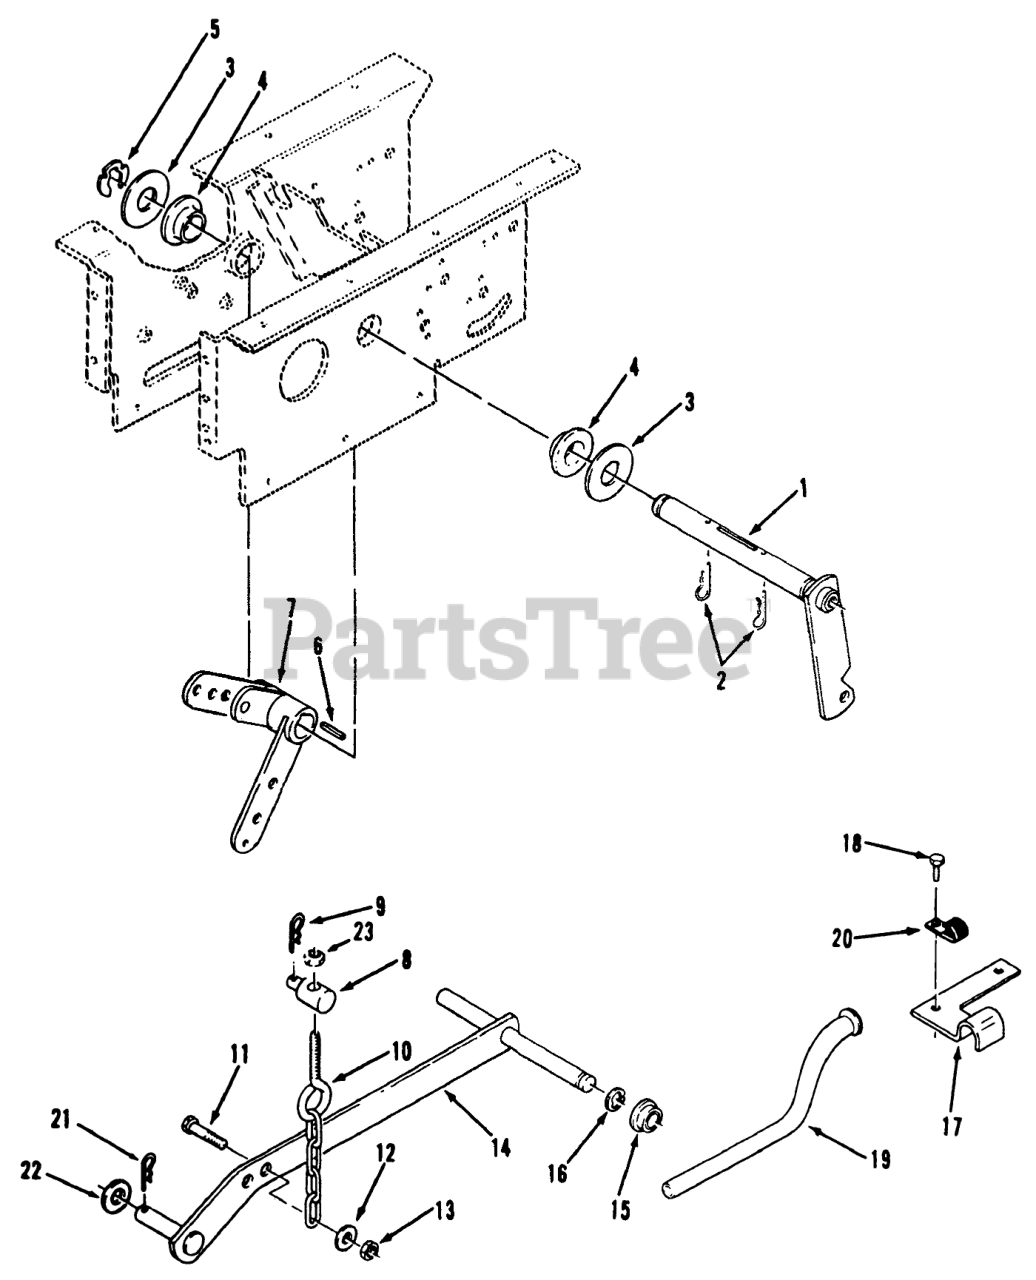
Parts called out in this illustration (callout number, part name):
1	WLDMT-LIFT ARM
2	Pin-Cotter
3	WASHER-FLAT
4	BEARING-FLANGE
5	Retainer
6	KEY-SQUARE
7	LIFT LEVER ASM
8	TRUNNION-LIFT
9	Hairpin Cotter
10	CHAIN-LIFT
11	SCREW-HH
12	WASHER-PLAIN
13	NUT-LOCK, NI
14	Bar-Lift
15	BUSHING
16	E Ring
17	CLAMP-CONDUIT R
18	SCREW-HH, LOCK
19	TUBE-CONDUIT R
20	CLIP
21	Hairpin Cotter
22	WASHER-FLAT
23	NUT-LOCK, NI
